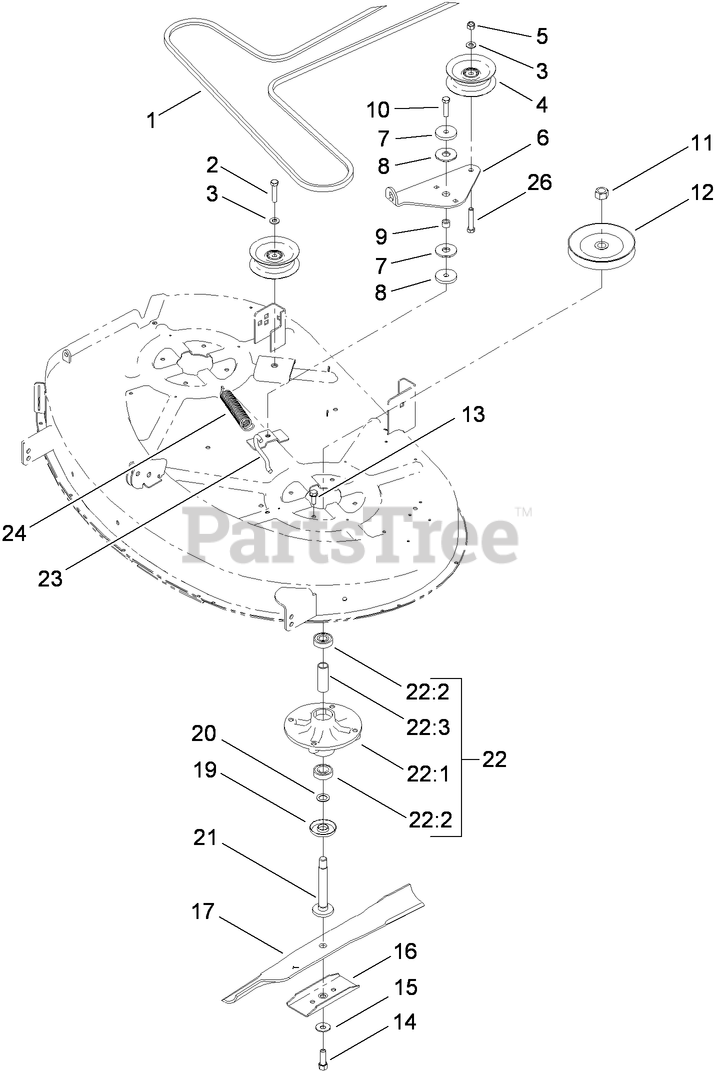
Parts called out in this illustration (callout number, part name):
1	V-BELT
2	SCREW-HH
3	WASHER-FLAT
5	NUT-LOCK, NI
6	ARM-IDLER
7	WASHER-PLAIN
8	WASHER-FRICTION, COMPOSITE
9	SPACER
10	SCREW-HH
11	NUT-HEX
13	SCREW-TAPTITE
14	SCREW-HH
15	WASHER-BELLEVILLE
16	STIFFENER-BLADE
17	BLADE-21.6 INCH
19	SHIELD-BEARING
20	SPACER
21	SHAFT-SPINDLE
22	Loose Parts Package
22:1	HOUSING-SPINDLE
22:3	SPACER
23	HOOK-RETURN, SPRING
24	SPRING-EXTENSION
26	SCREW-HH
